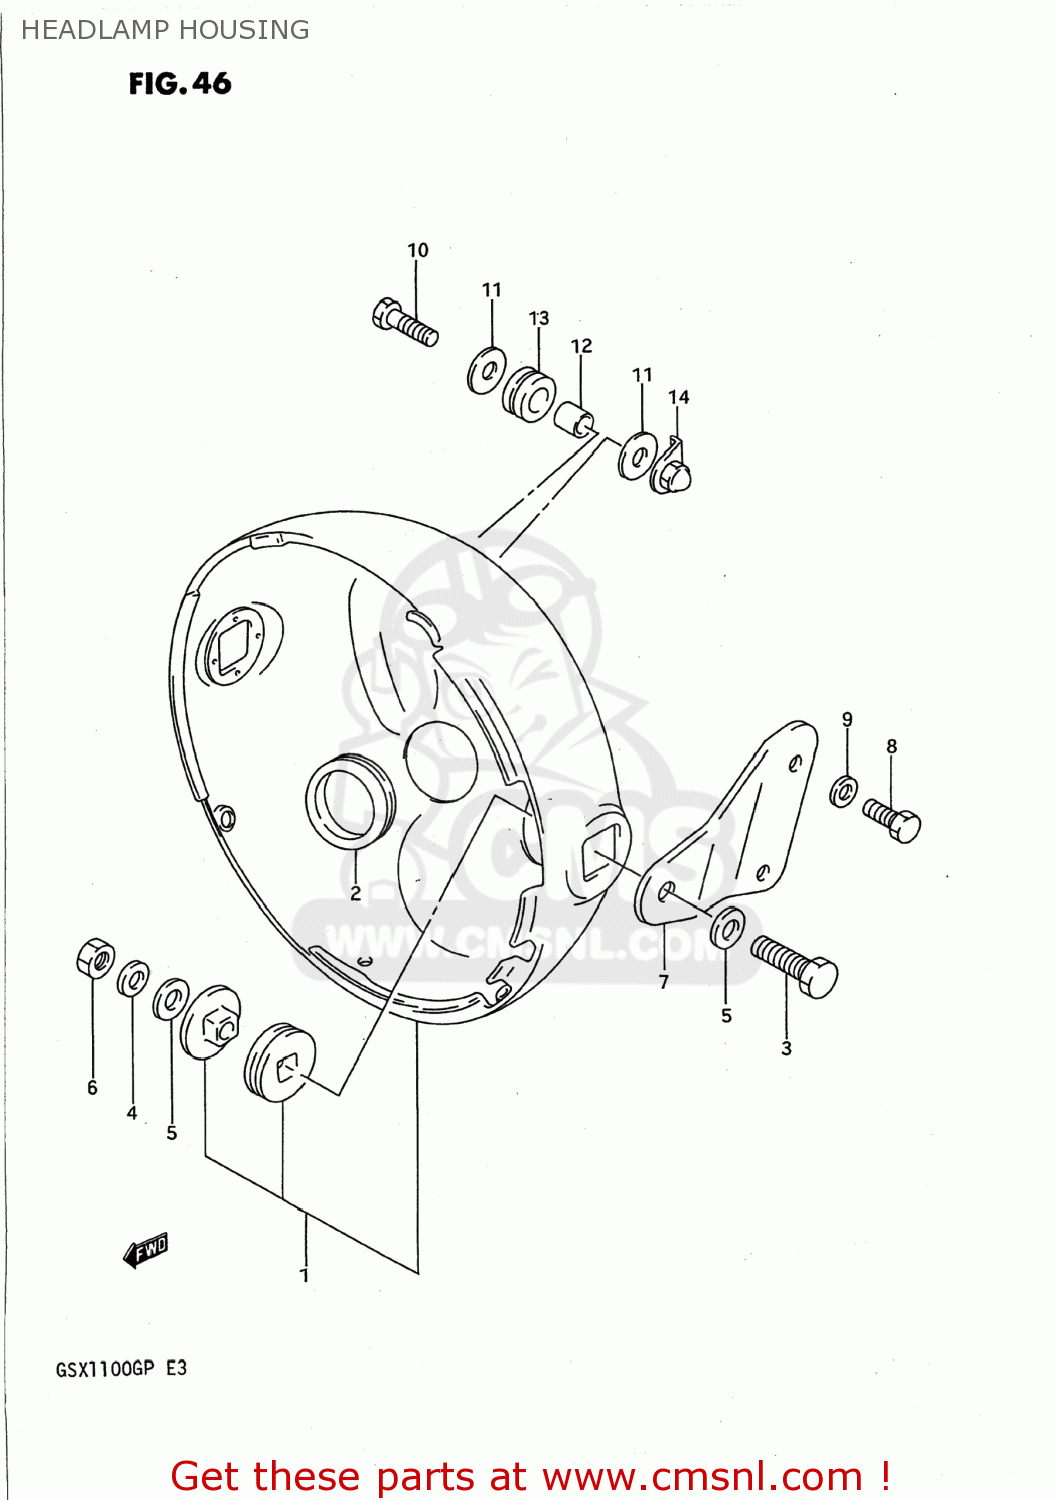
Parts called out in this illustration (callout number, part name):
1	HOUSING,HEADLAMP
2	GROMMET
3	BOLT
4	LOCK WASHER
5	WASHER
6	NUT
7	STAY,HEADLAMP HOUSING,R
8	BOLT
9	WASHER
10	BOLT
11	WASHER
12	SPACER(6.5X10.5X12)
13	CUSHION
14	PLATE,HEADLAMP
